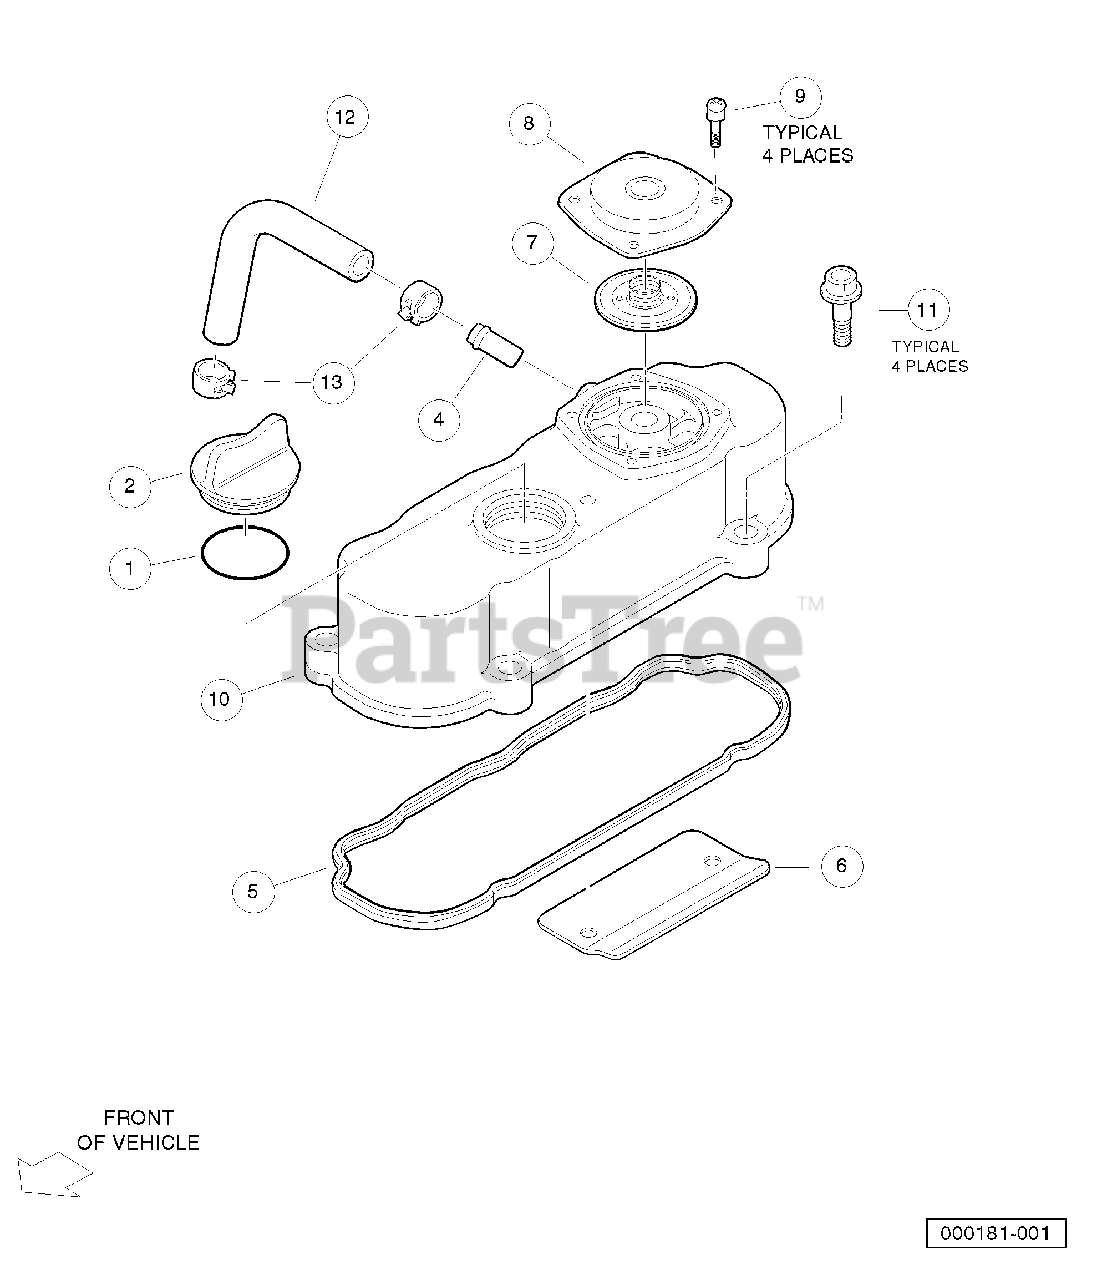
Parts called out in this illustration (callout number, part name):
1	O Ring, 30 X 36
2	Plug, Oil Filler
3	Assembly, Cylinder Head Cover
4	Pipe, Water Return, D722
5	Gasket, Cylinder Head Cover
6	Shield, Breather
7	Valve, Breather
8	Cover, Breather
9	Screw, Breather
10	Cover, Cylinder Head
11	Bolt, Cylinder Head Cover
12	Tube, Breather
13	Clamp, Breather Tube
